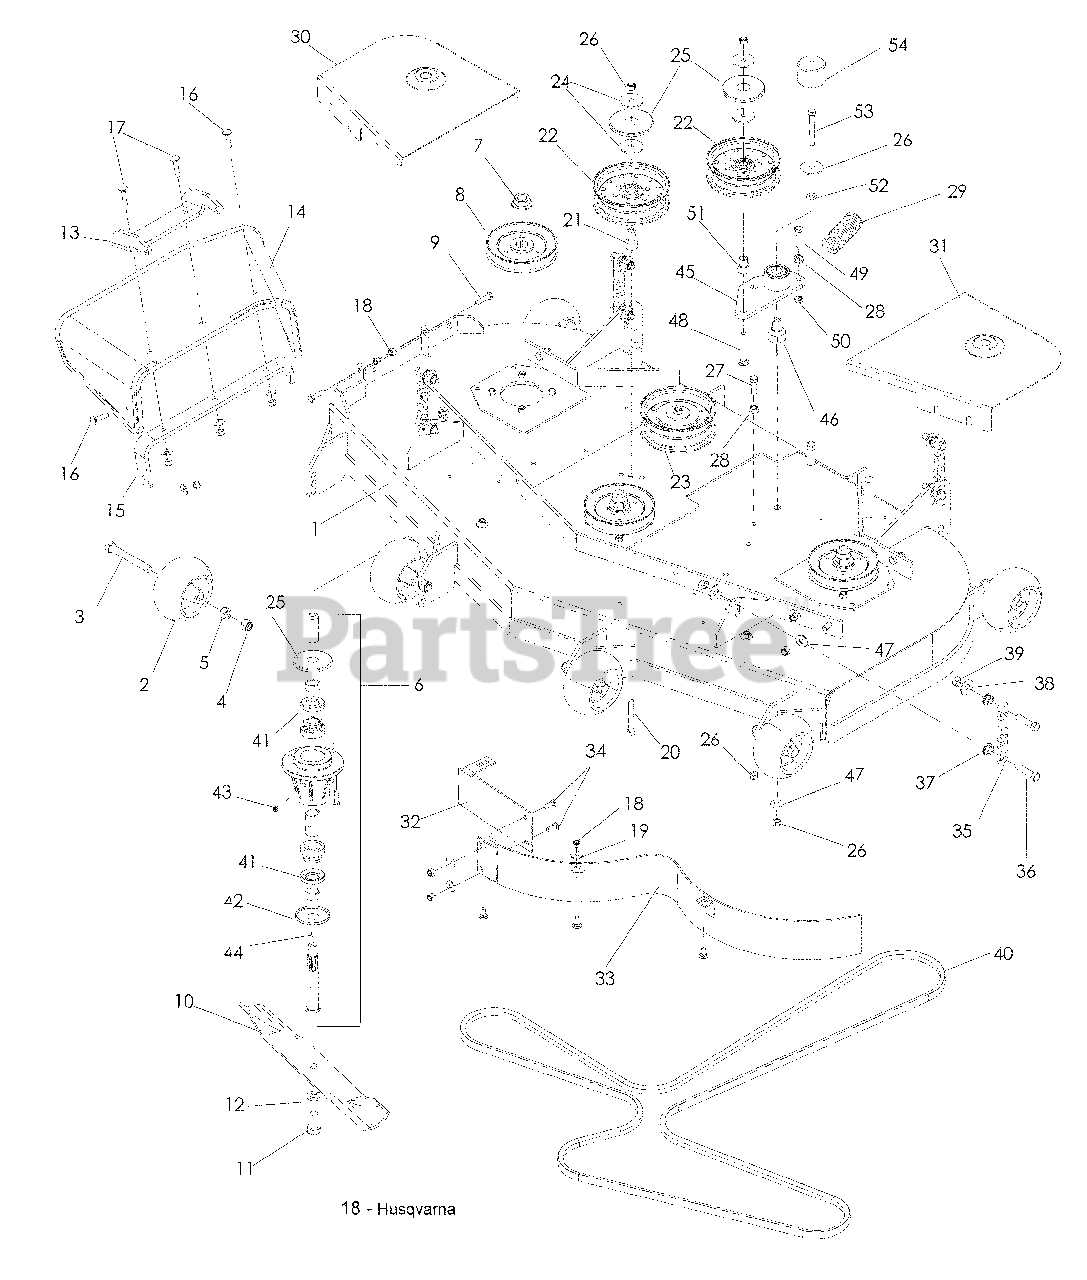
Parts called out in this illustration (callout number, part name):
1	DECK W/DECALS
2	WHEEL, GAUGE
3	HCS ½-13 x 4
4	NUT ½-13 HEX NYLOC
5	NUT ½-13 HEX
6	HOUSING ASSM, 52/61
7	NUT, FLANGE ¾-16
8	PULLEY, 52
9	HCS 5/16-18 x 1¼
10	BLADE, 18"
11	HCS 5/8-18 x 1¼
12	WASHER 5/8 SLW
13	PIVOT BRACKET, CHUTE
14	RUBBER CHUTE, 52/61
15	BRACKET, REINFORCE
16	RHSNB 5/16-18 x 1¼
17	RHSNB 5/16-18 x 1½
18	NUT 5/16-18 HEX NYLOC
19	WASHER 5/16 STD FLT
20	HCS 3/8-16 x 2¾
21	BUSHING, IDLER
22	PULLEY, IDLER
23	PULLEY IDLER
24	WASHER 3/8 SPECIAL
25	TOP DUST CAP
26	NUT 3/8-16 HEX NYLOC
27	HCS 3/8-16 x 1¼
28	NUT 3/8-16 HEX WHIZLK
30	SHIELD RT 52
31	SHIELD LT 52
32	BAFFLE MAIN
33	BAFFLE CENTER
34	RHSNB 5/16-18 x ¾
35	LIFT CHAIN
36	HCS 7/16-14 x 1¾
37	NUT 7/16-14 HEX WHIZLK
38	WASHER 7/16 FLAT
39	NUT 7/16-14 HEX NYLOC
40	BELT, DECK 52"
41	SHAFT SEAL
42	BOTTOM DUST CAP
43	GREASE POPPET
45	ARM, IDLER, W/BEARINGS
46	PIVOT, BEARING
47	WASHER 3/8 STD FLT
48	RHSNB 3/8-16 x 2¾
49	HCS 3/8-16 x 1½ GR 8
50	NUT 3/8-16 HEX JAM
51	BUSHING, IDLER
52	WASHER 3/8 SAE FLT
53	HCS 3/8-16 x 3
54	CAP, VINYL
